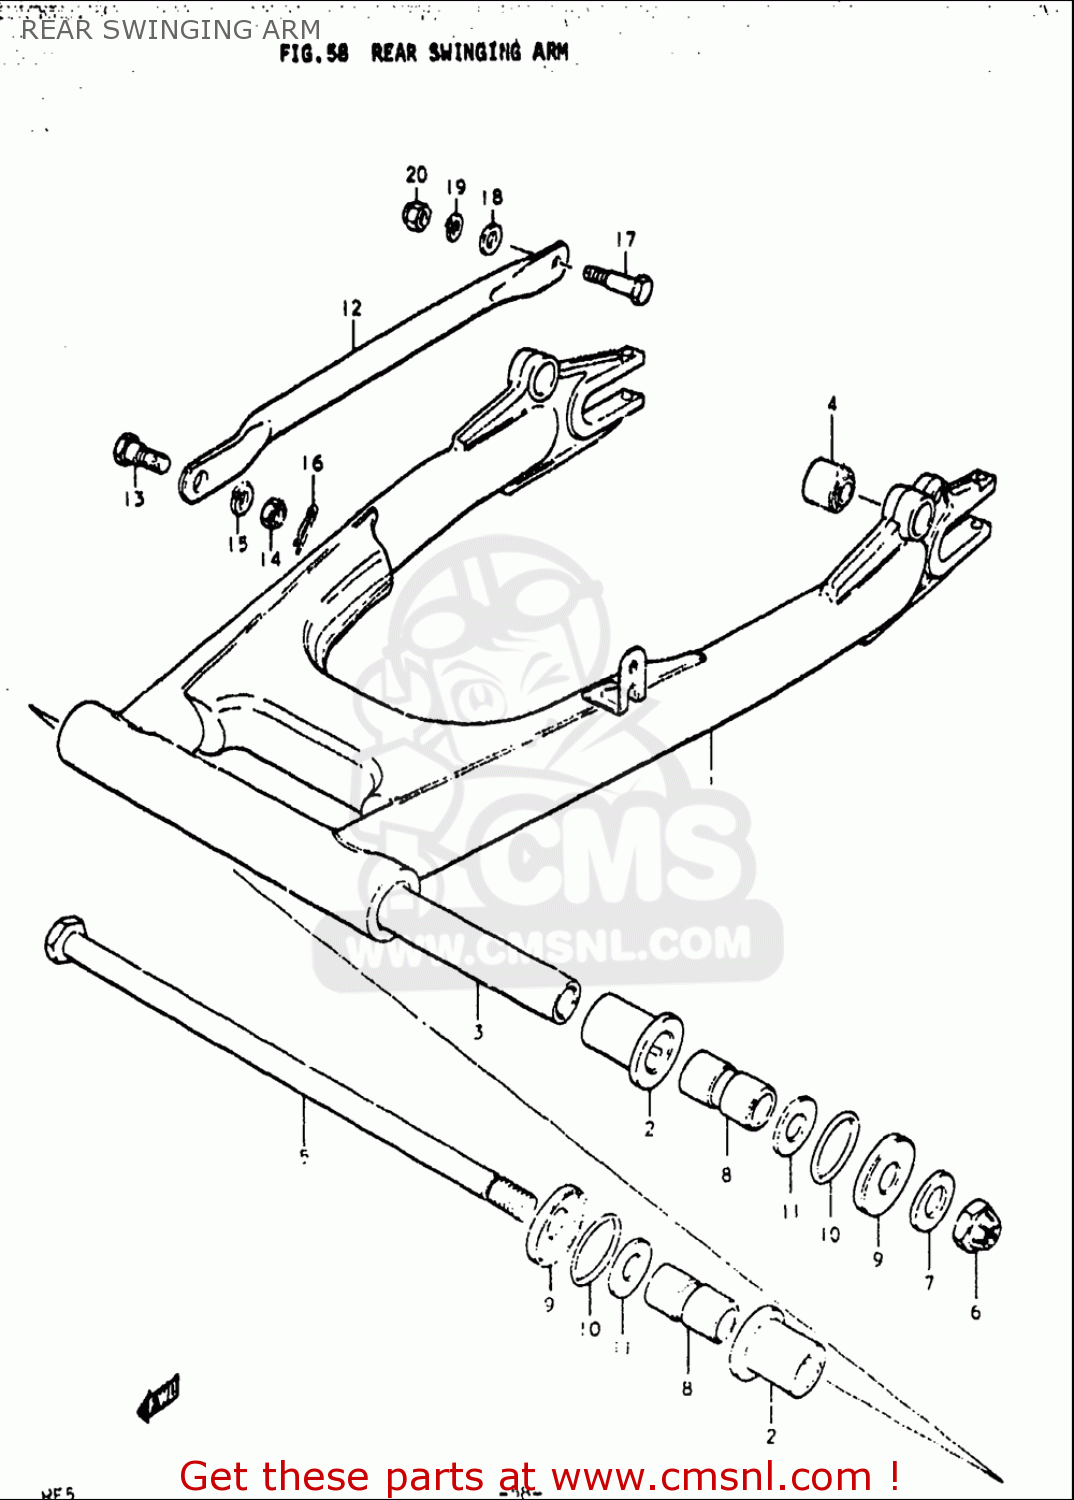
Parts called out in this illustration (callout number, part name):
2	BUSH
4	BUSH
5	SHAFT,REAR SWING ARM
7	WASHER
8	SPACER
9	COVER
10	O RING(D:3,ID:29.5)
11	WASHER(14.5X29X2.3)
13	BOLT(10X24.5)
14	NUT
15	WASHER,LOCK
16	CLIP
18	WASHER
19	WASHER,LOCK
20	NUT
